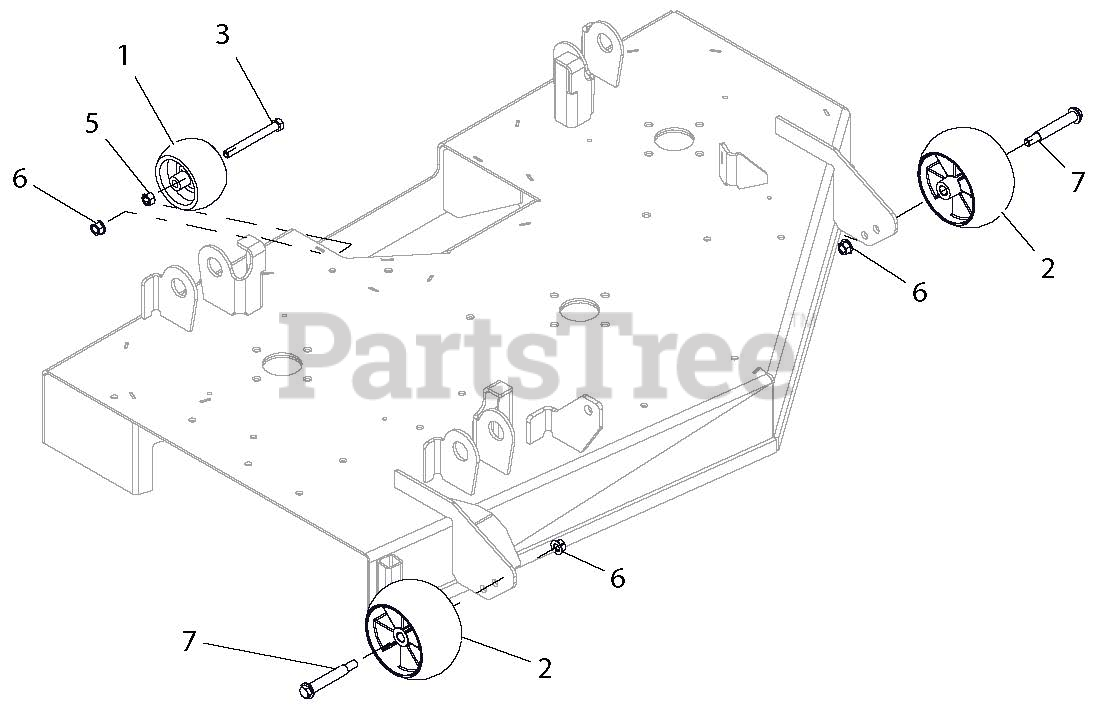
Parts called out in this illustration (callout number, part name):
2	ANTI-SCALP WHEEL - 5X OS
3	@BLT-HEX .38-16X3.50 GR5 YWZC
5	@NUT-HEX .38-16 YWZC
6	@NUT-LK-TOP-FLG .38-16 YWZC
7	BLT-SHLDR .38-16X2.50 HWH G5
